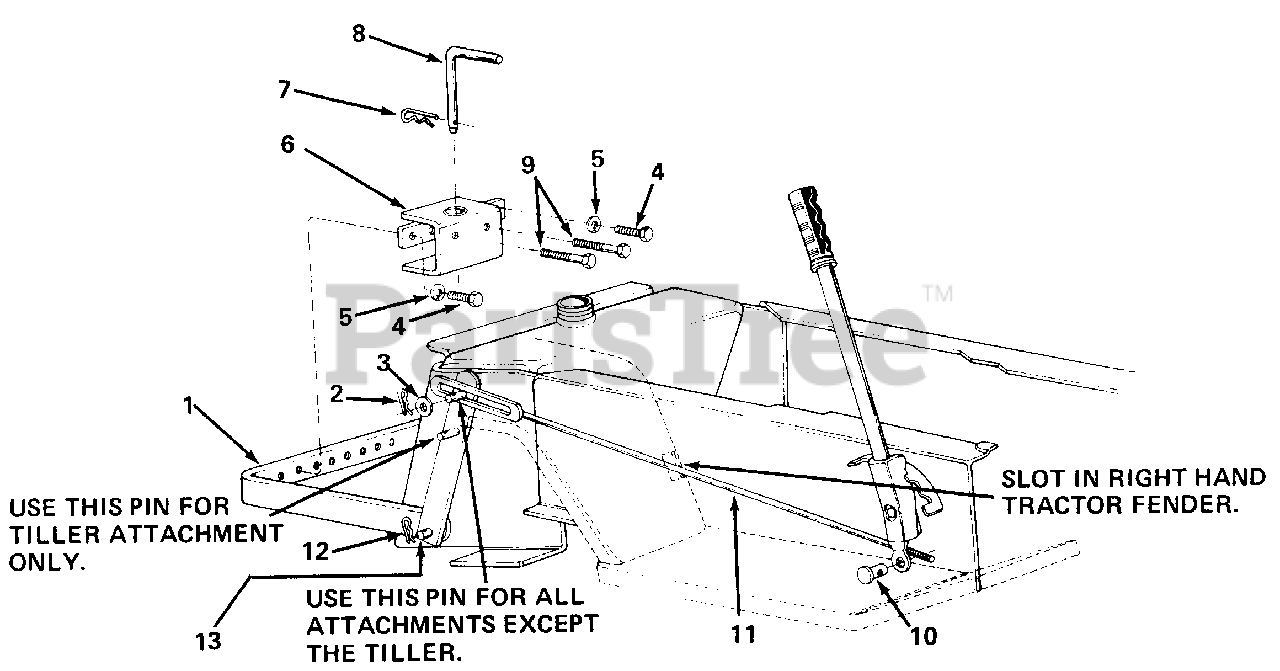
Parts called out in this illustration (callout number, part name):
3	Fl.-Wash. 1/2" I.D.
4	Hex Scr. 1/2-13 x 1.00" Lg.
5	L.-Wash. 1/2" Scr.
8	Hitch Pin
9	Hex Scr. 1/2-13 x 3.00" Lg.
10	Adjustment Ferrule
13	Hitch Rod
